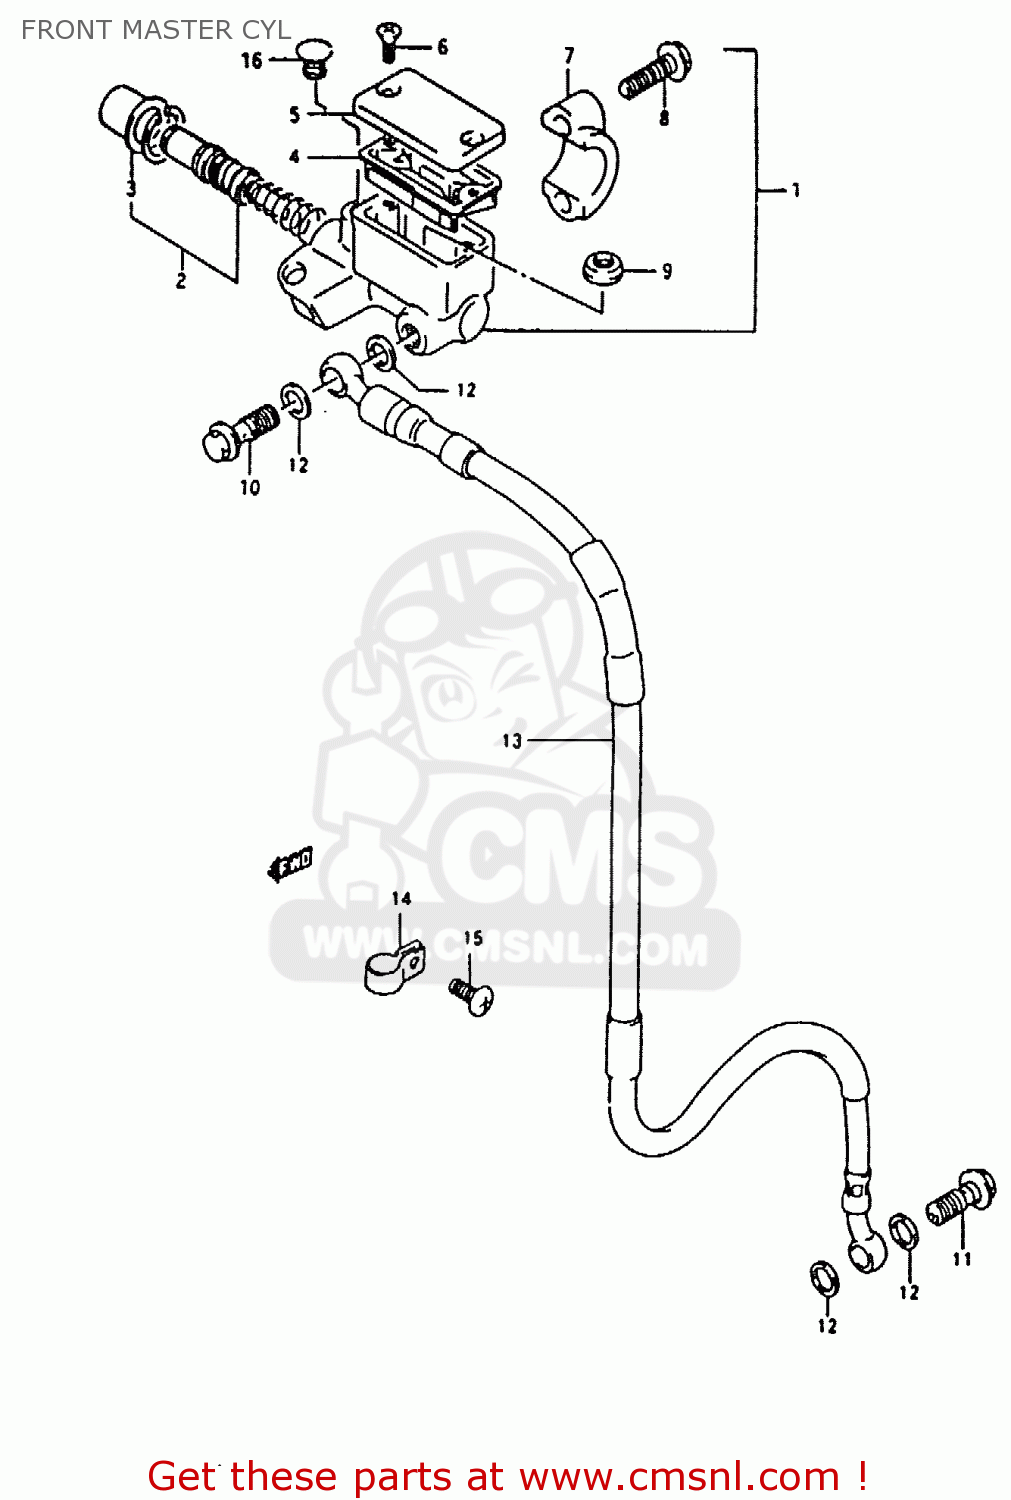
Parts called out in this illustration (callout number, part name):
1	CYLINDER ASSEMBLY,FRONT MASTER
2	PISTON & CUP SET
3	BOOT
4	DIAPHRAGM
5	CAP
6	SCREW
7	HOLDER
8	BOLT
9	SEPARATOR
10	BOLT UNION
11	BOLT UNION
12	WASHER(10X15X1.5)
13	HOSE COMP,FRONT BRAKE
14	CLAMP,FR BRAKE
15	BOLT
16	CAP(OD:14)
17	CLAMP,FRONT BRAKE HOSE
